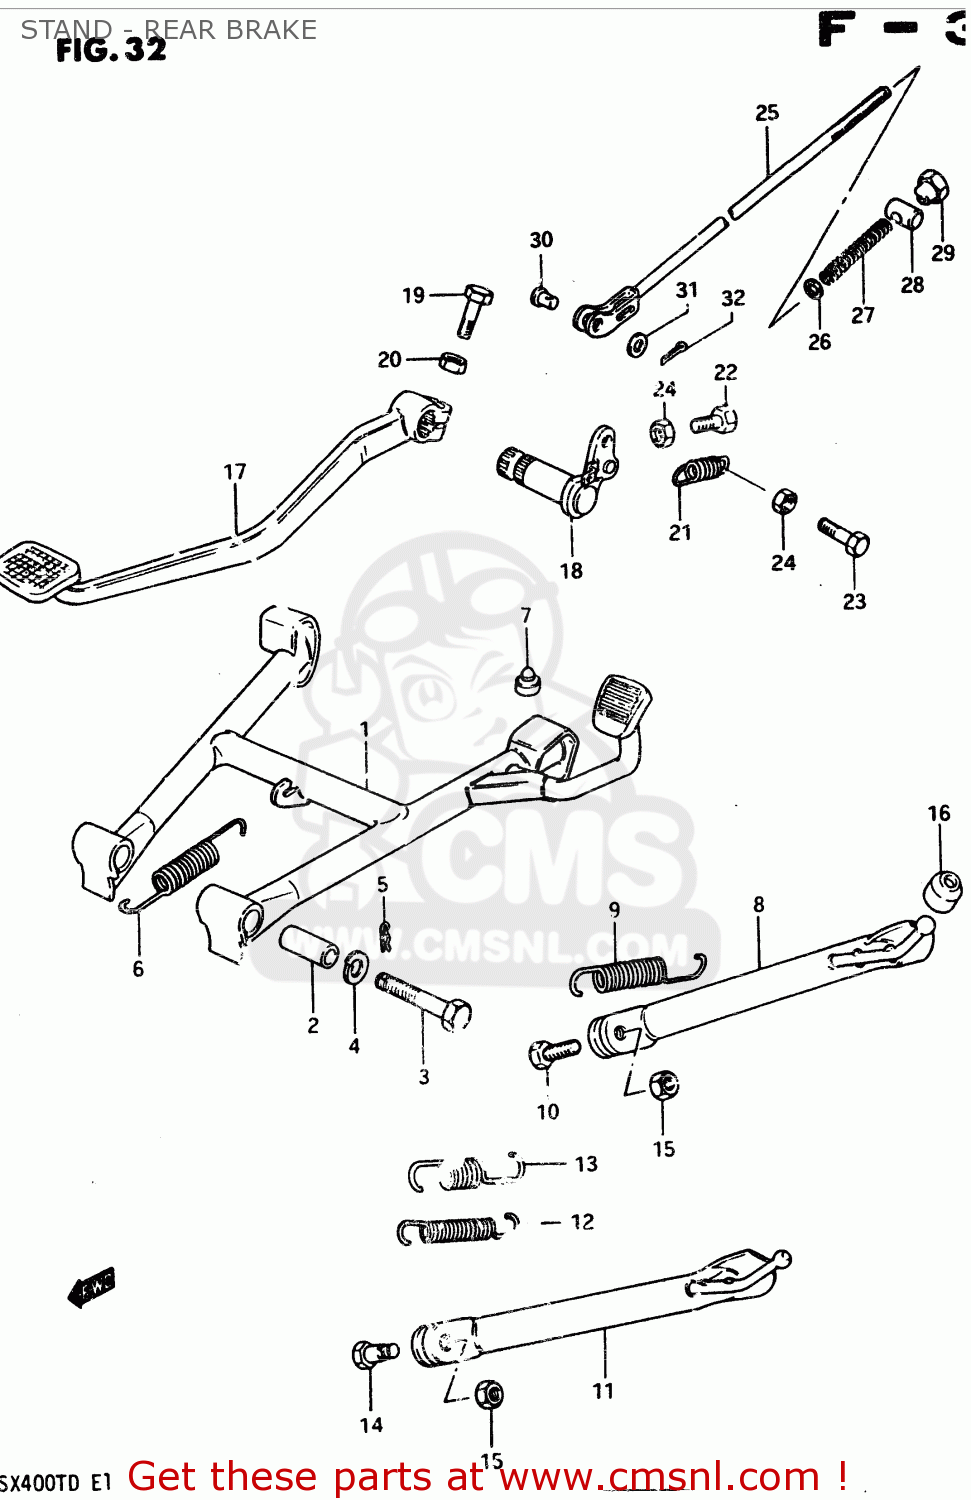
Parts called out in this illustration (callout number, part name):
1	STAND,CENTER
2	BOLT
3	BOLT
4	5
5	CLIP
6	SPRING
7	CUSHION
8	STAND,SIDE
9	SPRING
10	BOLT(10X30)
11	STAND, PROP
12	SPRING
13	SPRING, OUTER
14	BOLT L:30
15	NUT
16	CUSHION
17	PEDAL,BRAKE
18	ARM,BRAKE PEDAL
19	BOLT
20	LOCK WASHER
21	SPRING
22	BOLT
23	BOLT
24	NUT
25	ROD ASSY,RR BRAKE
26	WASHER
27	SPRING
28	PIN
29	NUT (6MM)
30	PIN(L:13.5)
31	WASHER
32	COTTER PIN
